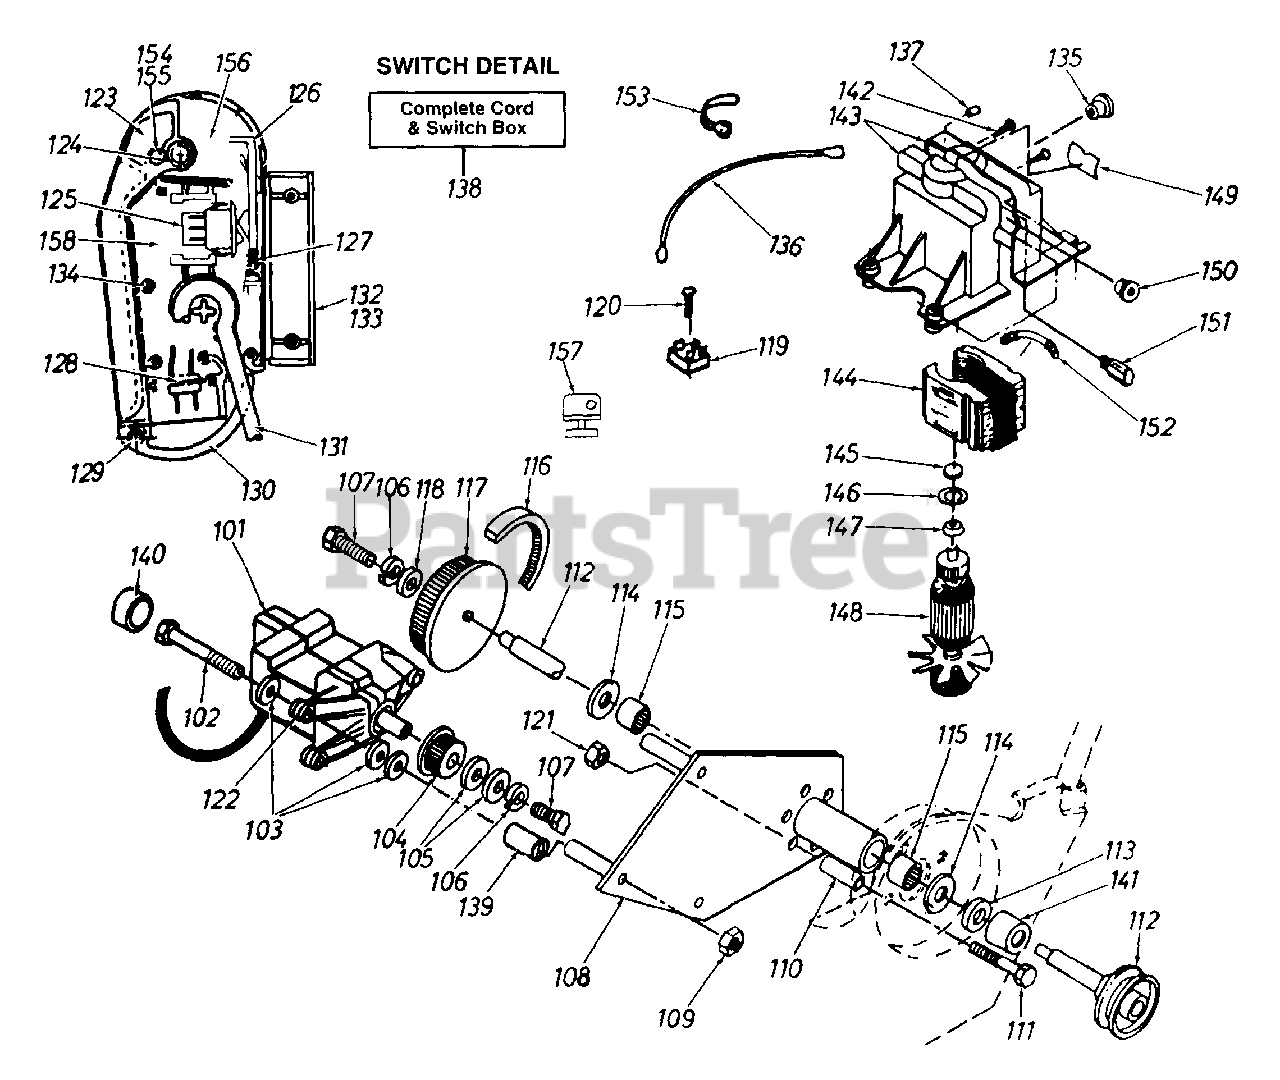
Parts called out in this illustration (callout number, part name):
101	Motor and Switch Box Ass'y.
102	Hex Bolt 1/4-20 x 3-1/4" Lg. Grade 5 (Special)
103	Washer 1/4"
104	Pulley - Motor (227)
105	Washer (Special)
106	L-Wash. 1/4" I.D.
107	Hex Bolt 1/4-20 x 3/4" Grade 5 (Special)
108	Plate Assembly
109	Lock Nut 1/4-20 Thd.
110	Spacer
111	Hex Bolt 5/16-18 x 1-1/2" Lg.
113	Fl-Wash. .635" I.D.
114	Washer - Thrust
115	Bearing - Needle
116	Belt - Cog
117	Pulley - Shaft (71T)
118	Washer - Special
119	Rectifier
120	Tap Scr. #10-24 x 3/4"
121	Lock Nut 5/16-18 Thd.
122	Insulator - Motor Housing
123	Handle Dash Switch Actuator
124	Spring - Switch Handle
125	Switch
126	Latch
127	Spring - Latch
128	Plug - 2 Prong
129	Spring - Cord Retainer
130	Cord Retainer
131	Cord Assembly
132	Housing - Upper Half
133	Housing - Lower Half
135	Bushing - Split
136	Jumper Wire Assembly (Blue)
137	Pad - Pressure
138	Cord & Switch Box Ass'y. Complete
139	Spacer Insulator
140	End Cap Insulator
141	Spacer
142	Screw - Motor Housing (Special)
143	Kit - Motor Housing (Both Halves)
144	Field Assembly
145	Oil Wick
146	"O"-Ring
147	Bearing - Spherical
148	Armature & Pulley Ass'y.
149	Spring - Field
150	Strain Relief
151	Brush Assembly
152	Wire Clip
153	Plastic Tie
154	Pin - Handle Lock
155	Spring - Handle Lock Pin
156	Plate - Key
157	Key - Switch Box
158	Jumper Wire Ass'y.
